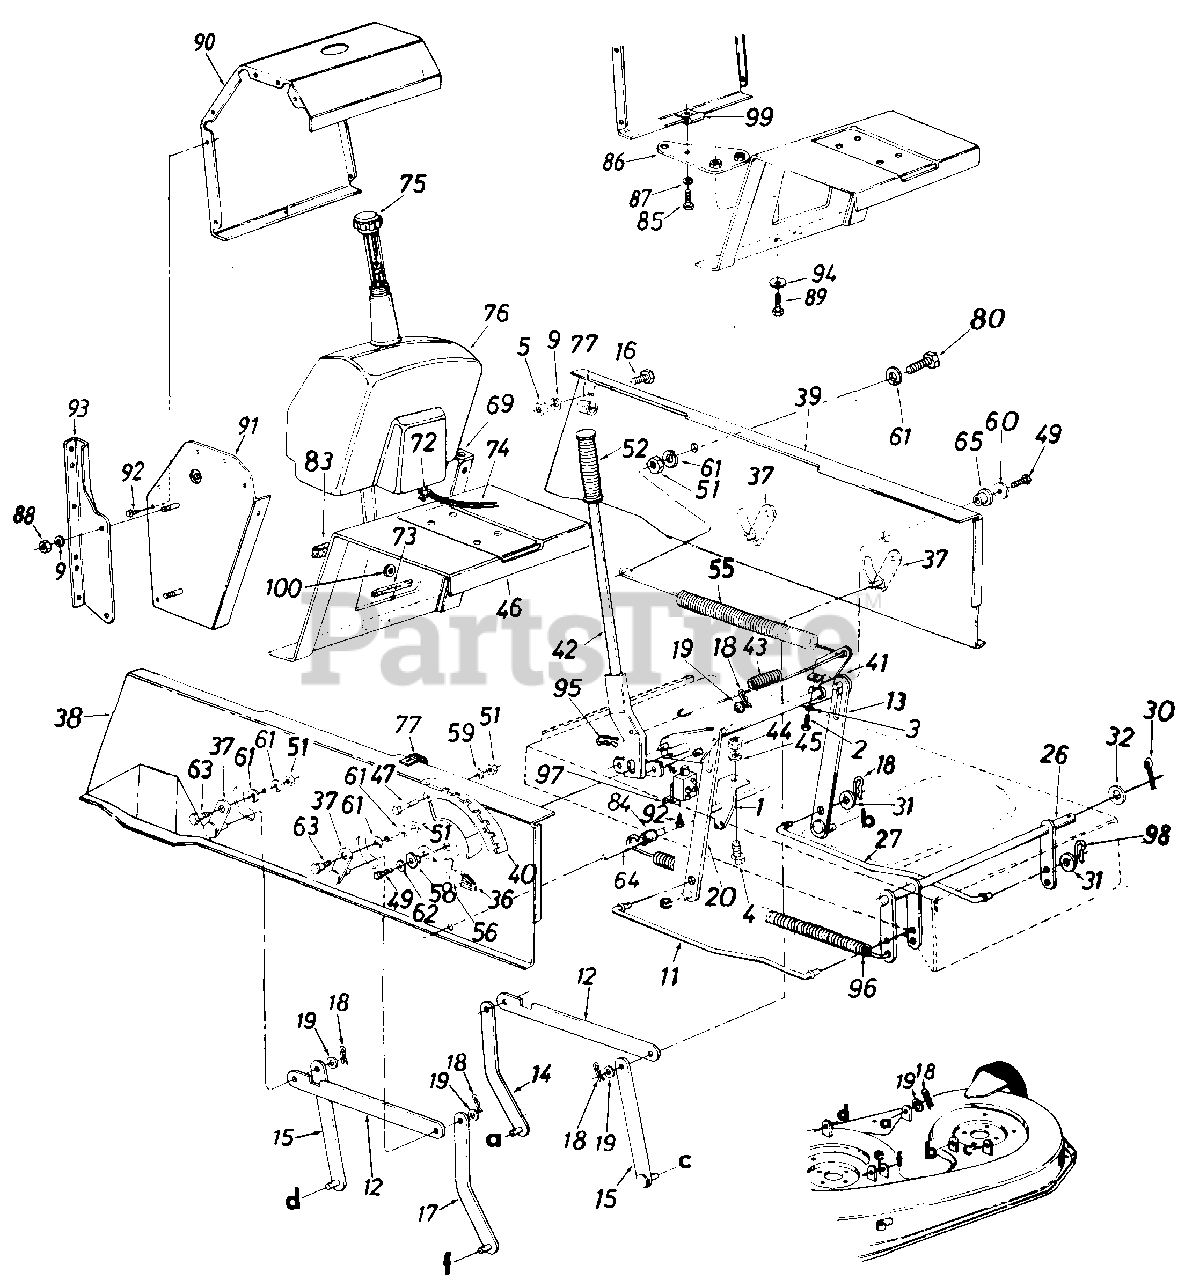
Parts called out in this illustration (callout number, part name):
1	Spring Hanger Bracket
2	Hex Tap. Scr. 5/16-18 x 1
3	Hex Jam Nut 5/16-18 Thd.
4	Hex Bolt 1/4-20 X .62" Lg.
5	Hex Nut 5/16-18 Thd.
9	L-Wash. 5/16" I.D.
11	Stabilizer Rod
12	Connecting Rod
16	Hex Bolt 5/16-18 x .75" Lg.
17	Deck Hanger Link Ass'y.-
18	Inter. Cotter Pin 1/2" Dia.
19	Fl-Wash. .531 I.D. x .93" O.D.
20	Deck Lift Link Ass'y.
26	Stabilizer Shaft Ass'y.
27	Stabilizer Rod
30	Cotter Pin 1/8" Dia. x 1.25"
31	Fl-Wash. .385" I.D. x .620" O.D.
32	Fl-Wash. .635" I.D. x 1.12" O.D.
36	Knob-Height Adj.
37	Pivot Link Ass'y.
38	Side Panel Upper Frame-R.H.
39	Side Panel Upper Frame-L.H.
40	Index Brkt.
41	Lift Shaft Ass'y.
42	Lift Handle Brkt. Ass'y.
44	Hex Nut 1/4-20 Thd.
45	L-Wash. 1/4" I.D.
46	Hitch Plate
47	Hex Bolt 5/16-18 x .75" Lg.
49	Hex Wash. TT-Tap Scr. 5/16-18 x .62" Lg.
51	Hex Nut 5/16-18 Thd.
52	Grip
55	Ext. Spring 11" Lg.
56	Deck Lift-Down Stop
58	Flange Brg. .630" I.D.
59	L-Wash. 5/16" I.D.
61	Bell-Wash. .325" I.D. x .930" x.045"
62	Fl-Wash. .344" I.D. x 1.125" O.D.
63	Shld. Bolt .437" Dia. x .180
64	Running Board Rod
65	Flange Brg. .632" I.D.
72	Hose Clamp-.406" Dia.
73	Trim Strip-5" Lg.
74	Gas Line-68" Lg.
75	Gas Tank Cap
80	Hex Bolt 5/16-18 x 1.50" Lg.
83	Foam Strip 318" x 1-1/8" x 11/2" Lg.
84	Spacer .523" I.D. x .640" O.D. x 1.95" Lg.
85	Hex Bolt 5/16-18 x 1" Lg. Gr. 5
87	L-Wash. 5/16" I.D.
88	Hex Nut 5/16-18 Thd.
89	Self-Tap Scr. 3/4" Lg.
90	Gas Tank Housing
91	Side Panel-R.H.
92	Truss Mach. B-Tap Scr. #10 x .50" Lg.
93	Mounting Bracket-R.H.
94	Bell-Wash. 3/8" I.D.
95	Internal Cotter Pin 3/8" Dia.
96	Ext. Spring 13.25" Lg.
97	Safety Switch
98	Cotter Pin 3/32" Dia.
